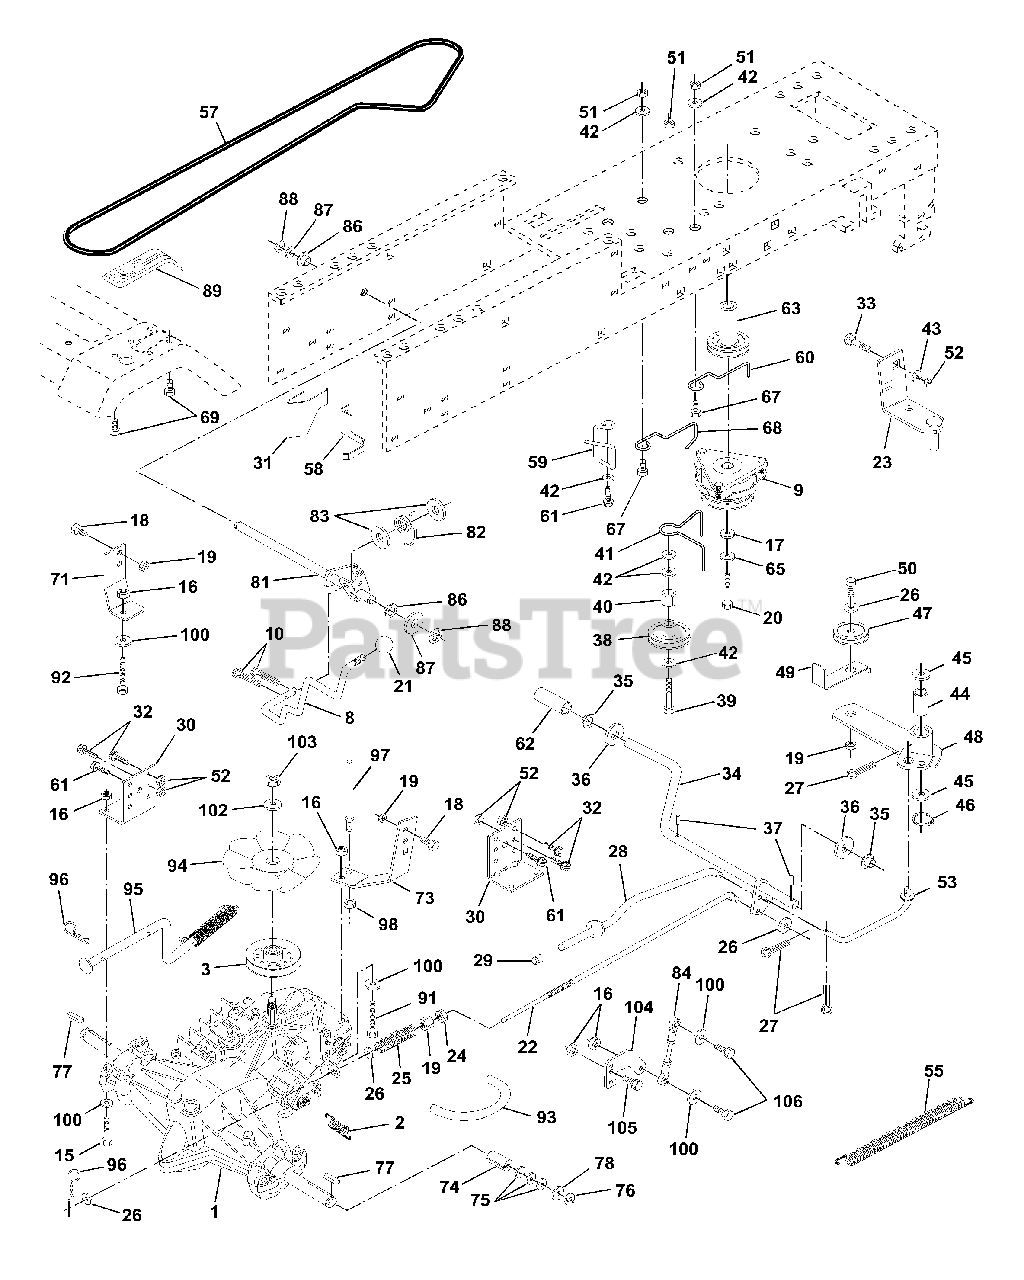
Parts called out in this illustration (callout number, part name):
1	Transaxle Assembly
2	Spring, Return, Brake
3	Pulley, Transaxle
8	Rod Shift Hydro LT
9	Clutch Elect 105 Ft/Lb
10	Pin Cotter 1/8 x 1 CAD
15	Bolt Fin Hex 5/16-18 Unc
16	Nut Lock Hex W/Ins. 5/16-18 Unc P
17	Washer 1-1/2 OD x 15/32 ID x .250
18	Bolt Fin Hex 3/8-16 Unc x 1 Gr.5
19	Nut Lock Hex W/Wsh 3/8-16 Unc
20	Bolt, Hex
21	Knob, Deluxe 1/2-13
22	Rod, Brake Hydro
23	Bracket Asm Mtg Cl
24	Nut
25	Spring, Brake Rod
26	Washer
27	Pin Cotter 1/8 x 3/4 CAD.
28	Rod, Parking Brake
29	Cap,Parking Brake
30	Bracket, Transaxle
31	Keeper Belt Lh
32	Bolt Hex Hd 5/16-18 Unc x 3/4
33	Bolt Carriage 5/16-18 x 3/4
34	Shaft, Foot Pedal
35	Bearing, Nylon
37	Pin, Roll
38	Pulley, Idler, Flat
40	Spacer Split
41	Keeper, Belt Retainer
42	Washer 13/32 x 13/16 x 12 Gauge
43	Washer 11/31 x 5/8 x 12 Ga.
44	Bearing, Nylon
45	Washer, Hardened
46	Ring, Klip
47	Pulley, Idler, V-Groove
48	Bellcrank Assembly
49	Retainer, Belt
50	Bolt
52	Nut Crownlock 5/16-18 UNC
53	Link, Clutch
55	Spring, Return, Clutch
57	V-Belt, Ground Drive
58	Keeper Belt Lh Hydro 0750.18/20"
59	Keeper, Center Span
60	Keeper Belt Engine
61	Screw Thdrol. 3/8-16 x 3/4 Ty. TT
62	Cover, Pedal
63	Pulley, Engine
65	Washer
67	Bolt
68	Keeper Belt Engine
71	Strap Torque Lh Hydro 18/20" T
73	Strap Torque Rh Hydro 18/20" T
74	Spacer Split .80 x 1.70 Cad 13 UNC
75	Washer 25/32 x 1-1/4 x 16 Gauge
77	Key, Square
78	Washer 25/32 x 1-5/8 x 16 Gauge
81	Shaft Asm. Cross Hydro 20" Tires
82	Spring Torsion T/A
83	Washer 17/32 x 3/4 x 16 Ga.
84	Rod, Tie Hydro 20" Tires
86	Bushing Rod Strig. 629/632 ID
87	Washer 21/32 x 1-1/4 x 16 Ga.
88	Ring Klip #5304-62
89	Console, Shift
91	Bolt Fin Hex 5/16-18 x 2-1/4
92	Bolt Fin Hex 5/16-18 Unc x 1-1/2
93	Line Fuel Hydro 4"
94	Fan, Hydro 7"
95	Control Asm Bypass Hydro
96	Retainer Spring 1" Zinc/Cad
97	Keeper Belt Rh Hydro 0750.18/20"
98	Nut Keps Hex 3/8-16 Unc
100	Washer 11/32 x 3/4 x 16 Ga.
102	Washer Belleville .501D x 1.50D
103	Nut Nylon Insert 1/2-20 Unf
104	Arm, Control Hydro
105	Screw Cap Hex 5/16 x 18 x 1
106	Bolt Fin Hex 5/16-18 Unc x 1-1/4
